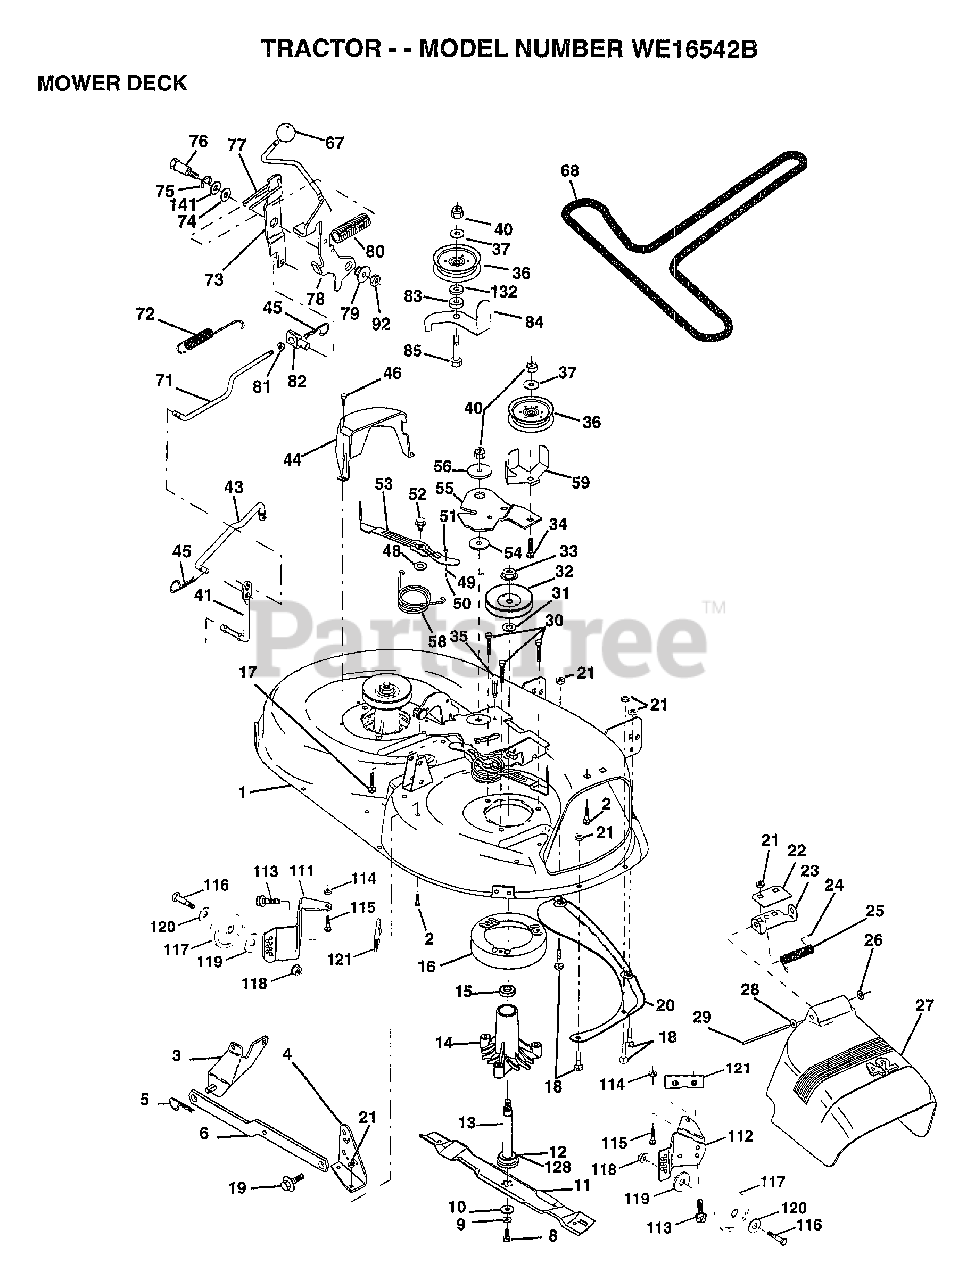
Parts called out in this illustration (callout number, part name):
1	"HOUSING ASSY.42"""
2	BOLT
3	BRKT ASM SWAY BAR
4	BRKT DECK SW BAR
8	BLADE BOLT
10	WASHER.HARD.BLADE
11	"BLADE.42"" HIPERF"
12	BEARING.BALL
14	HSG ASM MANDREL
15	BEARING
16	STRIPPER RND MWR
17	BOLT RDHD 3/8-16
18	BOLT
19	BOLT SHD 5/16-18
20	BAFFLE VORTEX 42
22	STIFFENER BRKT
23	DEFLECTOR BRKT
24	CAP-SLEEVE LT
25	SPRING TORSION
26	NUT PUSH M
27	DEFLECTOR.SHIELD
28	WASHER
29	HINGE ROD
30	"SCREW-THD ROLL,WA"
31	WASHER
32	PULLEY.MANDREL.42
34	BOLT
35	XMAS TREE FASTNER
36	FLAT IDLER PULLEY
37	WASHER
41	PIVOT ROD
43	ROD CLUTCH W/NIBS
44	GUARD MAND LH BLK
45	RETAINER M
46	SCREW.1/4-20X5/8
48	HARD SMALL WASHER
49	ROLLER ASM-CAM
50	SHOULDER BOLT
51	LOCKNUT
52	BOLT.SHLD.5/16-18
53	BRAKE PAD ARM ASM
54	HARDENED WASHER
55	ARM-IDLER
56	SPACER RETAINER
58	SPRING TORSN BRAK
59	GUARD IDLER TUV
67	KNOB.RD.7/16-14
68	BELT.V.T-PATH
71	ROD CLUTCH 38/42
72	RETURN SPRING
73	CLUTCH ARM SECOND
74	WASHER
75	RING
76	SHOULDER BOLT
77	SPRING KEEPER
78	LEVER.ASM.CLUTCH
79	BUSHING
80	SPRING.CLUTCH.MWR
81	NUT
82	TRUNION ADJ
83	WASHER
84	"KEEPER-BELT,FIXED"
85	BOLT
92	NUT
111	BRACKET.GWHL.LH.
112	BRACKET.GWHL.RH.
113	SCREW
116	BOLT M
117	WHEEL.GAGE.BLK.PL
118	LOCKNUT
119	WASHER
120	WASHER
121	BRACKET.EXTRD.GWL
128	WASHER.FELT.
132	WASHER GT
141	WASHER .T
